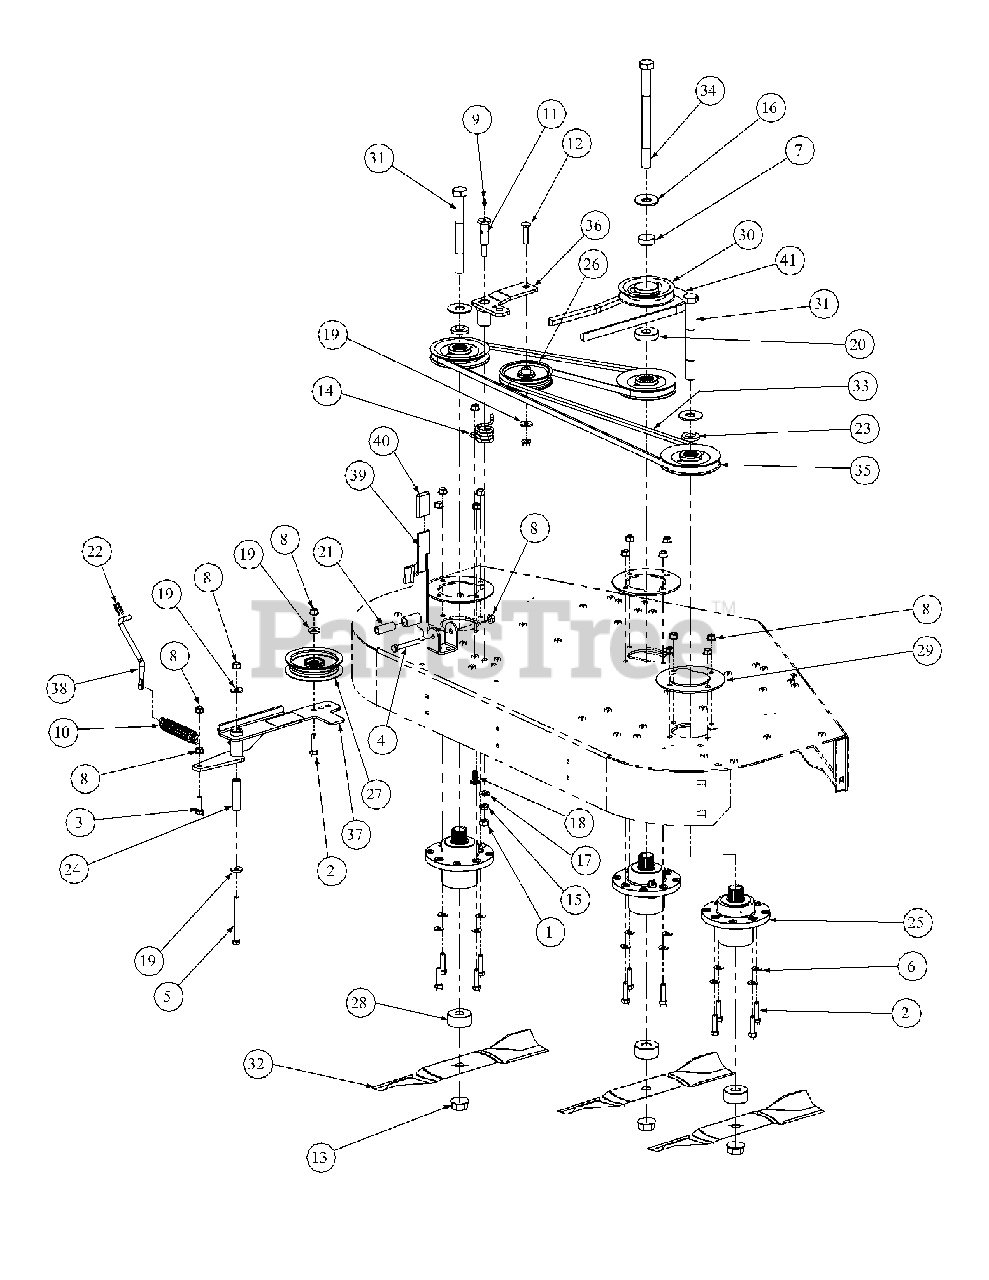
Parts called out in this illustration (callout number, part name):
1	Nut, 7/16-14
2	Hex Cap Screw, 3/8-16 x 1/2
3	Hex Cap Screw, 3/8-16 x 1-1/4
3	Hex Cap Screw, 3/8-16 x 3/4
4	Hex Cap Screw, 3/8-16 x 2-1/2
5	Hex Cap Screw, 3/8-16 x 4
6	Washer, 3/8 Zinc
7	Caster Spacer
8	Nut, 3/8-16, Hex Flange Lock
9	Grease Fitting, 1/4-28 x 3/16
10	Extension Spring, 1.0 OD x 5.0
10	Extension Spring, .865 OD x 4.68
11	Shoulder Screw, 7/16-14
12	Screw, 3/8-16 x 1.75
13	Nut, 3/4-16, Hex Flange
14	Idler Torsion Spring
15	Lock Washer, 7/16
16	Washer, .781 ID x 2.0 OD x .105
17	Washer, .469 ID x .875 OD x .105
18	Carriage Bolt, 3/8-16 x 1.0
19	Washer, .406 ID x .10 OD x .105
20	Spacer, .76 ID x 2.0 OD x .477
20	Spacer, .76 ID x 2.0 OD x .790
21	Spacer, .39 ID x .63 OD x 1.75
22	Cotter Pin
23	Spacer, .812 ID x .218
24	Spacer, .39 ID x .625 OD x 2.75
25	Aluminum Spindle Assembly
26	Flat Pulley
27	Idler Pulley, 4.06 OD
27	Idler Pulley, 5.25 OD
28	Spacer, .760 ID x 2.000 OD x 0.9
29	Spindle Support Plate, Cast Alum.
30	Pulley, 4.75 OD
31	Hex Cap Screw, 3/4-16 x 7.00
32	Blade, 17.0, Hi-Lift. 0.756 ID
33	Belt, A Section x 105.3
34	Hex Cap Screw, 3/4-16 x 9.00
35	Cast Pulley, 5.00 OD
36	Idler Arm Assembly, Mower Deck
36	Idler Arm Assembly Casting, Mower Deck
37	Idler Arm Assembly
38	Spring Tension Rod
39	Handle Tension Weldment
40	Handle Tension Grip
41	Belt, B Section x 83.2
